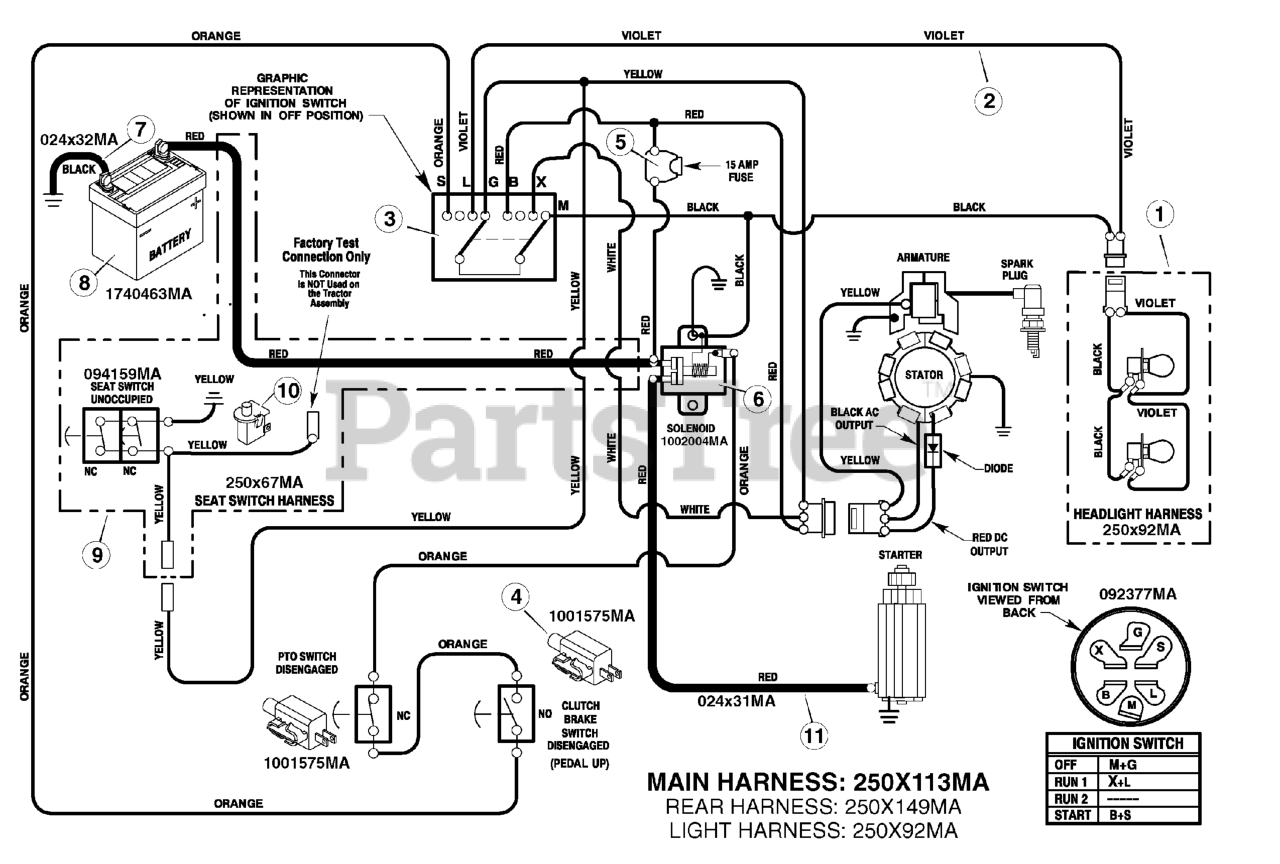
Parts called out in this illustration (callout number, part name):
1	Harness, Light Wire
2	Harness, Chassis Wire
3	Switch, Ignition
4	Switch, Limit
6	Solenoid
7	Cable, Battery Ground
9	Harness, Seat Switch Wire
10	Switch, Seat Sensor
